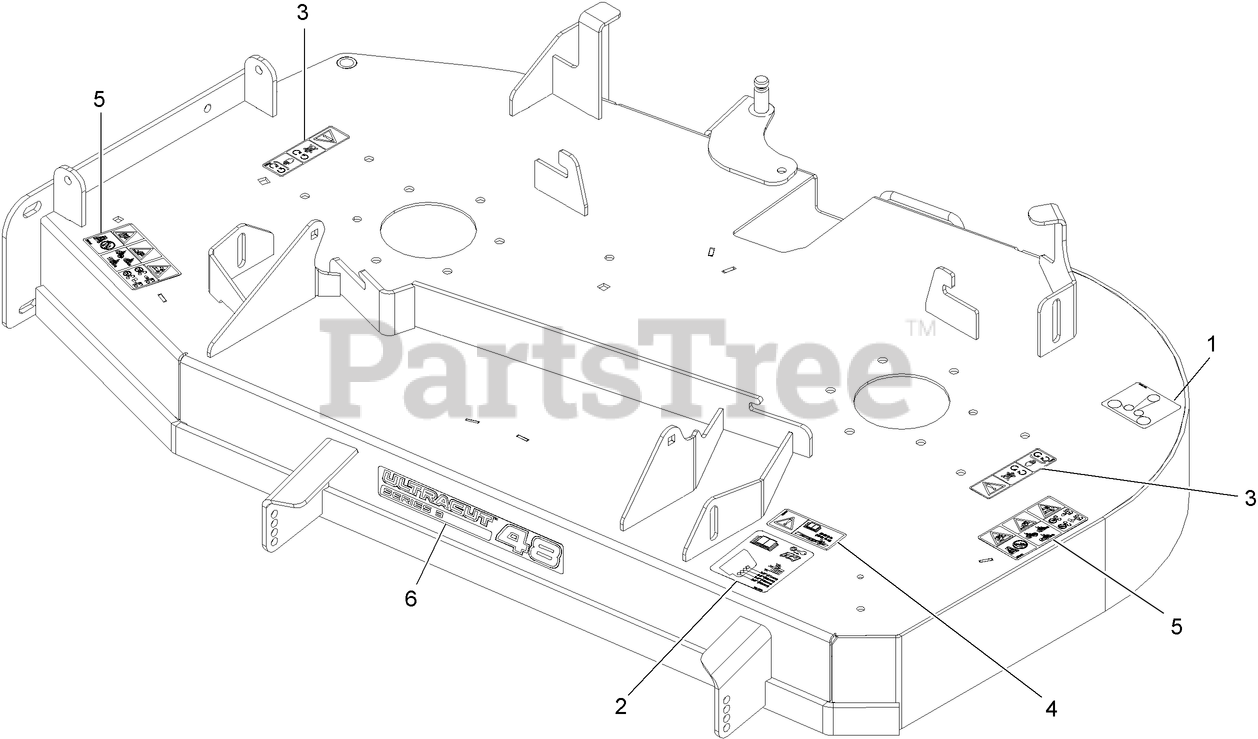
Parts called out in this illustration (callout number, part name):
1	DECAL-ROUTING, BELT
2	DECAL-ROLLER, ANTI-SCALP
3	DECAL-COVER, MISSING
4	DECAL-TORQUE, BOLT
5	DECAL-DANGER THROWN OBJECTS
6	DECAL-ULTRACUT 48 SERIES 3
